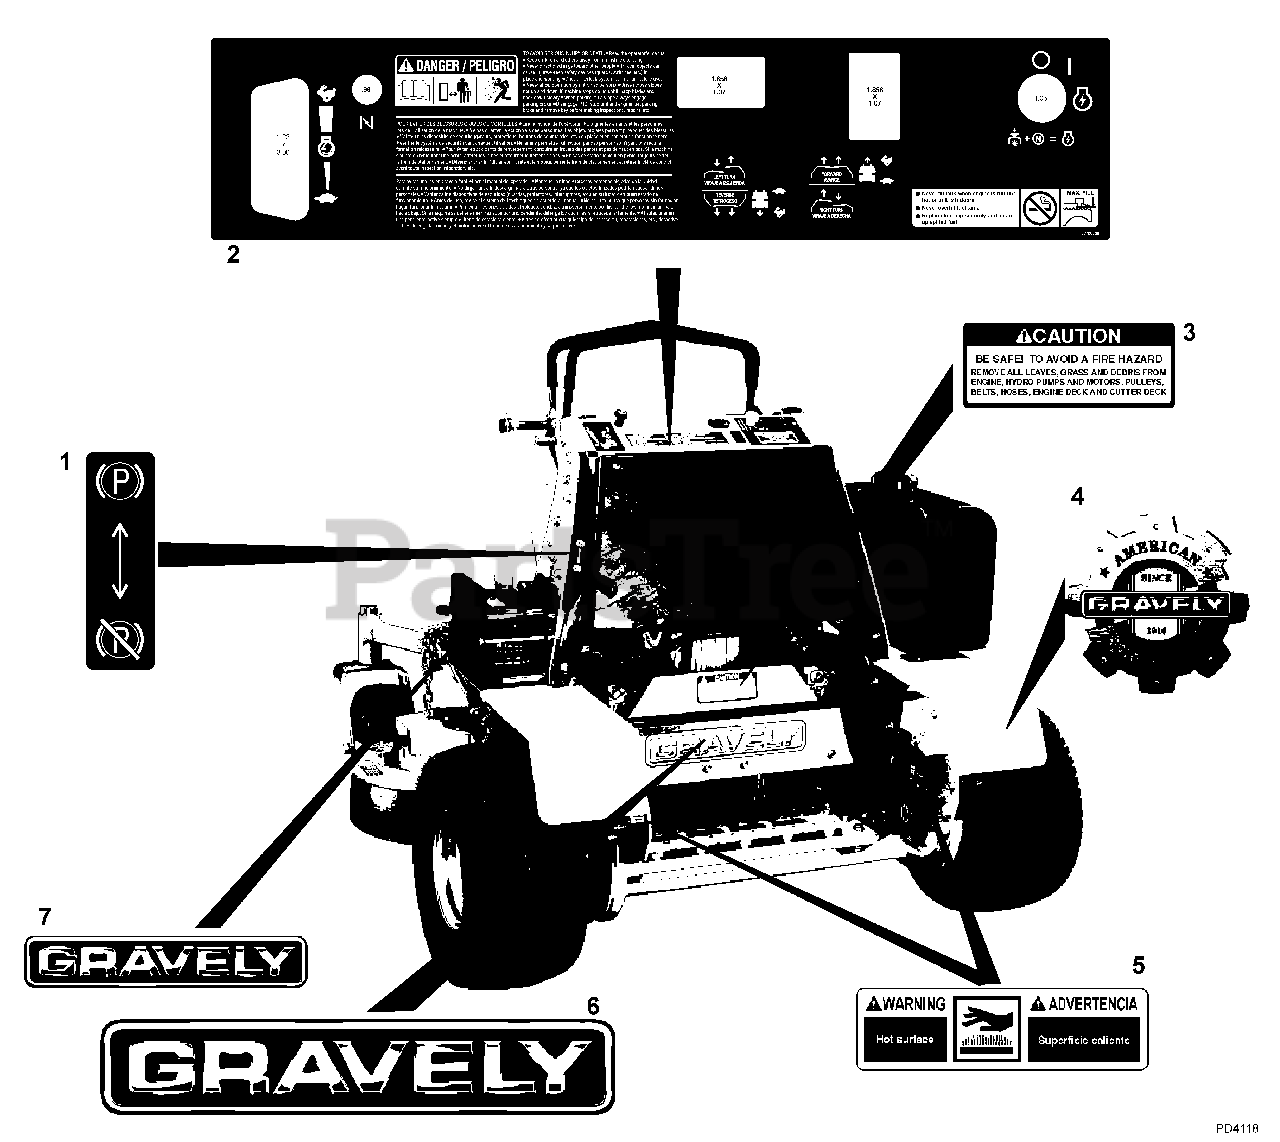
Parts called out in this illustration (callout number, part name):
1	Decal, Park Brake Direction
2	Decal, Console Gravely Prostance
3	Decal, Debris
4	Decal, Gravely Heritage - Large
5	Decal, Warning, Hot Surface
6	Decal, 15" Gravely Logo
7	Decal, 6.5" Gravely Logo
